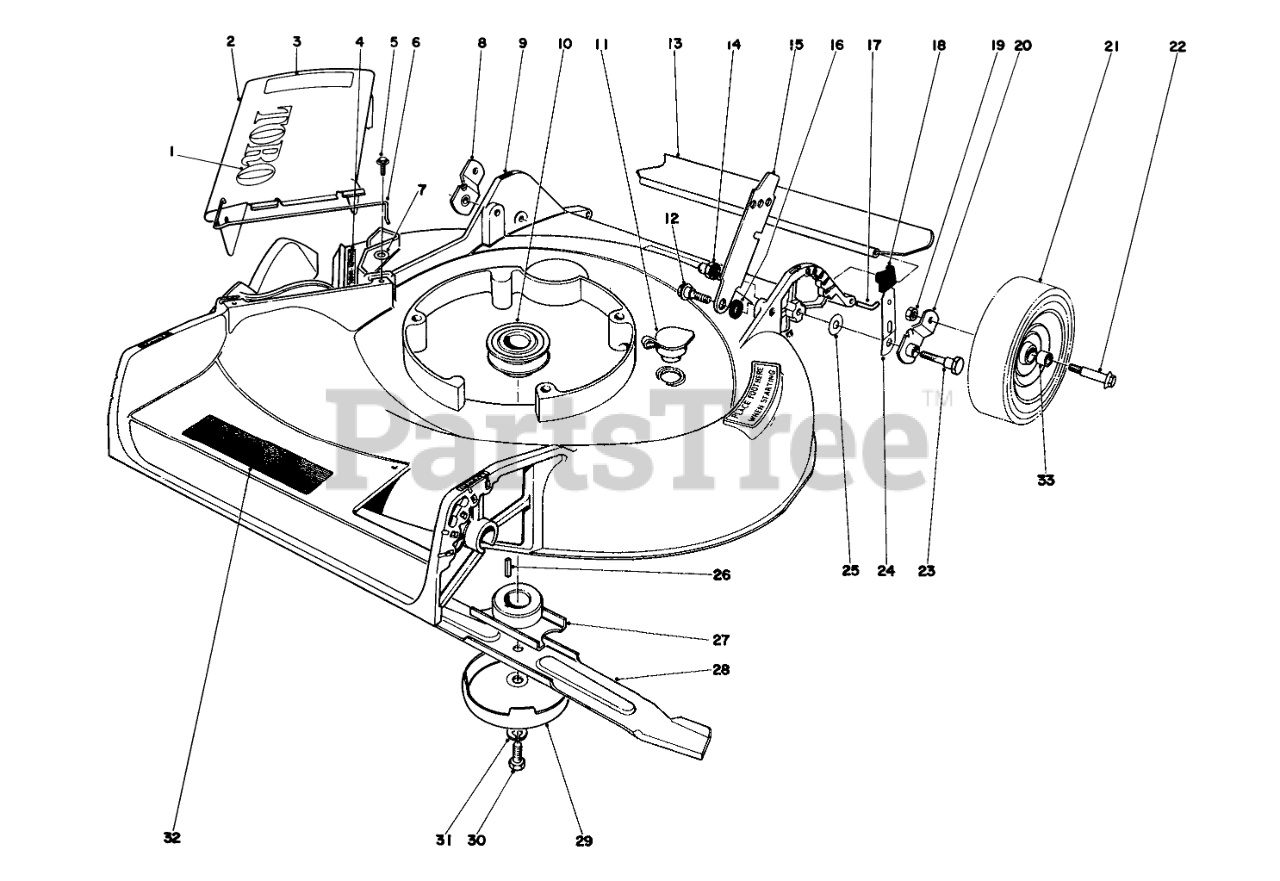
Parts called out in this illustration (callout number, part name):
1	TORO LOGO DECAL
2	Deflector Cover Assembly (Incl. Ref. #1, 3 & 6)
3	Caution Decal
4	Decal
5	SCREW
6	SPRING HINGE
7	WASHER-FLAT
8	Pivot Arm
9	Housing
10	DRIVER PULLEY
11	WASHOUT PLUG
12	SCREW-SHOULDER
13	REAR SAFETY SHIELD 21
14	HANDLE PIVOT NUT
15	Latch
16	SPACER
17	SHIELD ROD
18	KNOB-ARM
19	Nut
20	Pivot Arm
21	WHEEL TIRE ASM 8 IN
22	BOLT-WHEEL
23	5/16-18 PIVOT SCREW
24	SPRING ARM ASM
25	WASHER-PIVOT
26	KEY-SQUARE
27	Blade Retailer
28	Blade
29	AntiScalp Cup
30	SPECIAL SCREW
31	WASHER-LOCK
32	Decal-Deck
33	BUSHING
